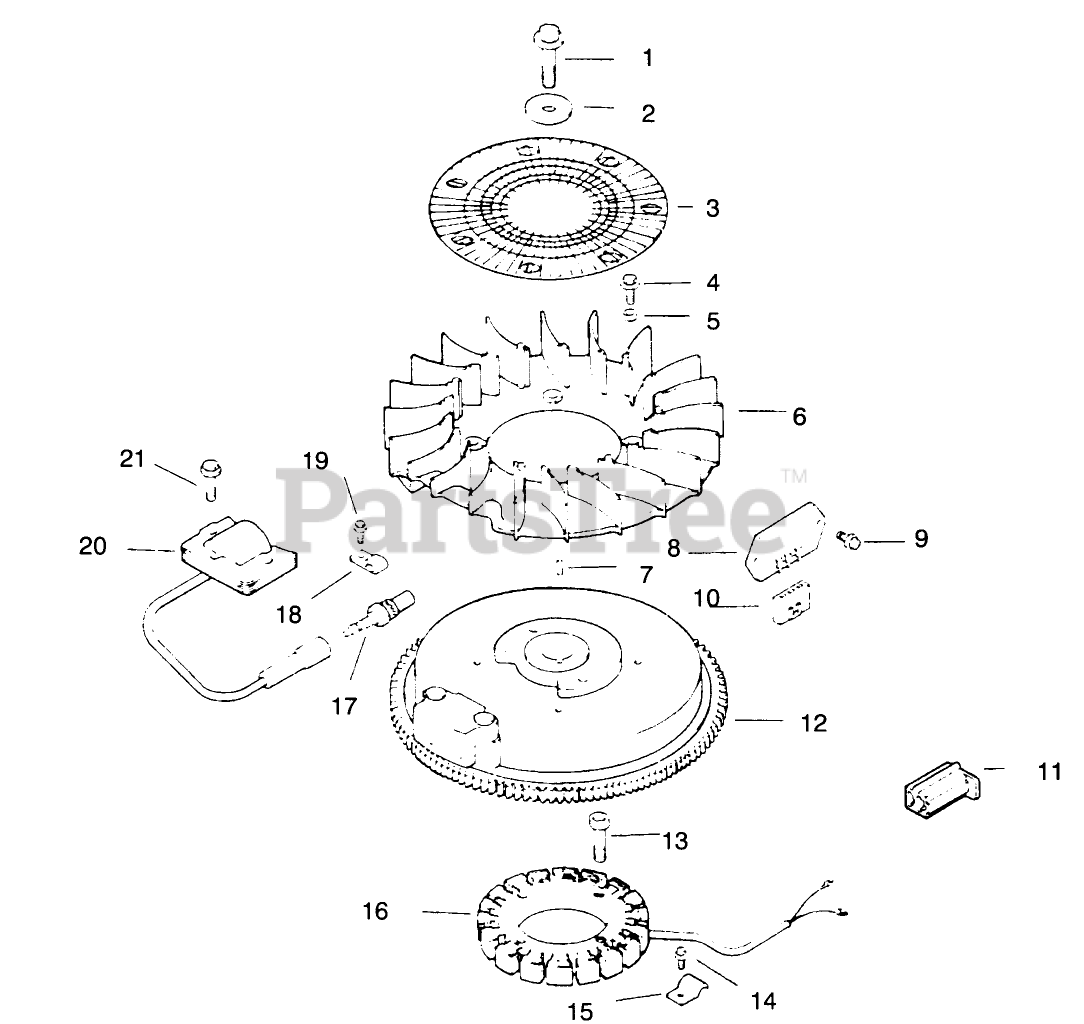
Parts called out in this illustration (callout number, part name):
1	Screw
2	Washer-Flat
3	Screen-Grass
4	Screw
5	Spacer
6	Fan
7	Key
8	Rectifier-Unregulated
9	Screw
10	Connector
11	Connector
12	Flywheel ASM
13	Screw
14	Screw
15	Clip-Stator Harness
16	Stator-15 Amp
17	Plug-Spark
18	Clip
19	Screw
20	Module-Ignition
21	Screw
